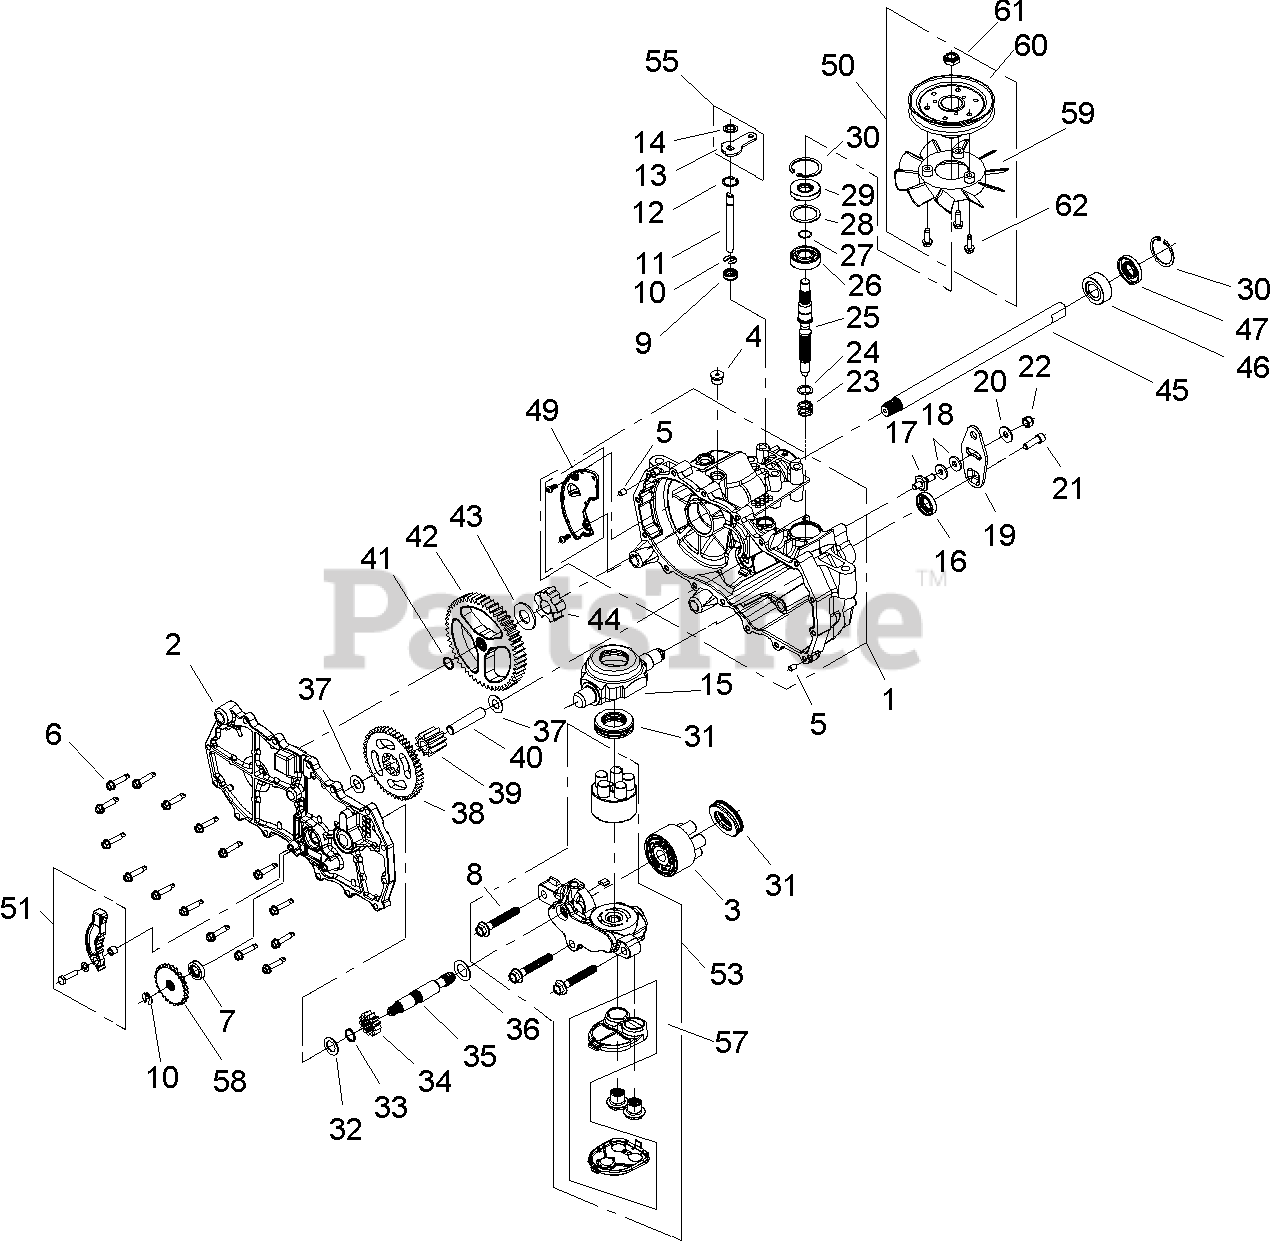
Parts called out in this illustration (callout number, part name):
1	LH MAIN HOUSING ASM
2	LH SIDE ASM
3	CYLINDER BLOCK ASM
4	PLUG-THREAD, STRAIGHT
6	SCREW-HHF
9	SEAL-LIP
10	RING-RETAINING, EXT
11	ROD-BYPASS
12	RING-RETAINING, INT
13	ARM-BYPASS
14	RING-RETAINING, EXT
15	SWASHPLATE-TRUNNION
18	PUCK-FRICTION
19	ARM-CONTROL
20	WASHER-PIVOT
23	SPRING-BLOCK
24	WASHER-BLOCK, THRUST
25	SHAFT-INPUT
26	BEARING-BALL
27	RING-RETAINING
30	RING-RETAINING
31	BEARING-THRUST
32	WASHER-FLAT
33	RING-RETAINING
34	GEAR-PINNION, 13T
35	SHAFT-MOTOR
36	WASHER-SHAFT, MOTOR
39	GEAR-JACKSHAFT, 10T
40	PIN-JACKSHAFT
41	RING-RETAINING, SPIRAL
42	GEAR-BULL, 52T
44	BEARING-SLEEVE
45	AXLE
46	BEARING-SLEEVE, OUTBOARD
49	LH EXPANSION PLATE KIT
50	FAN PULLEY KIT
51	BRAKE ARM KIT
53	LH 7-PISTON CENTER SECTION KIT
55	BYPASS ARM KIT
57	FILTER KIT
58	DISC-BRAKE, COG
59	FAN
60	PULLEY
